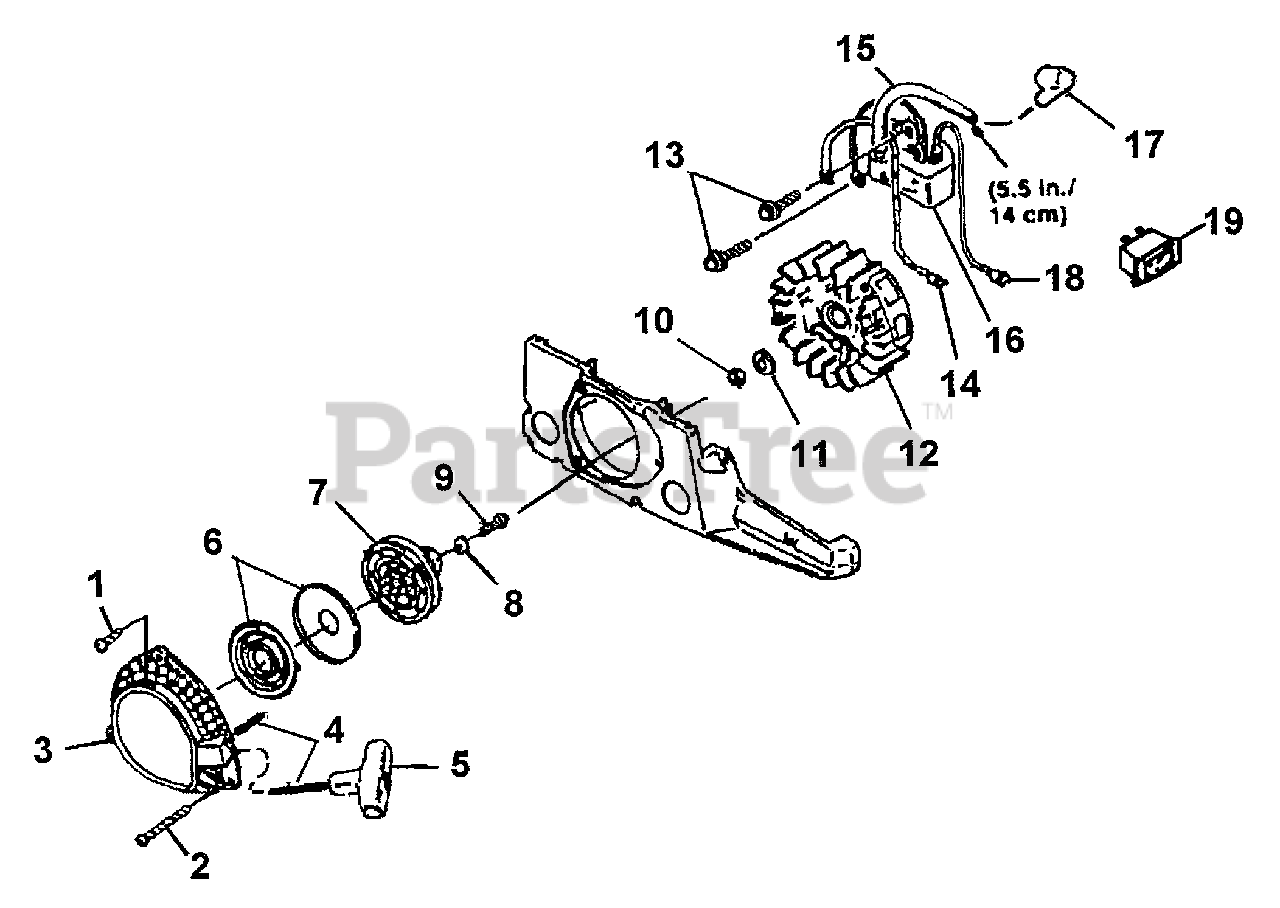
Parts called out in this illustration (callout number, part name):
1	SCREW-Thread Form (8-16 x 5/8")
2	SCREW-Thread Form (8-16 x 2")
3	STARTER - COMPLETE
4	ROPE, STARTER (46")
5	GRIP, STARTER
6	SPRING & CONTAINER
7	PULLEY
8	WASHER, RETAINING
9	SCREW Plastite (10-14 x 5/8")
10	NUT, LOCK
11	WASHER, FLAT
12	ROTOR & STARTER PAWLS
13	SCREW, Sems Hex Hd. (10-24 x 7/8")
14	IGNITION GROUND WIRE
15	SLEEVE, Insulating
16	IGNITION MODULE
17	SPARK PLUG BOOT KIT
18	IGNITION WIRE
19	SWITCH
